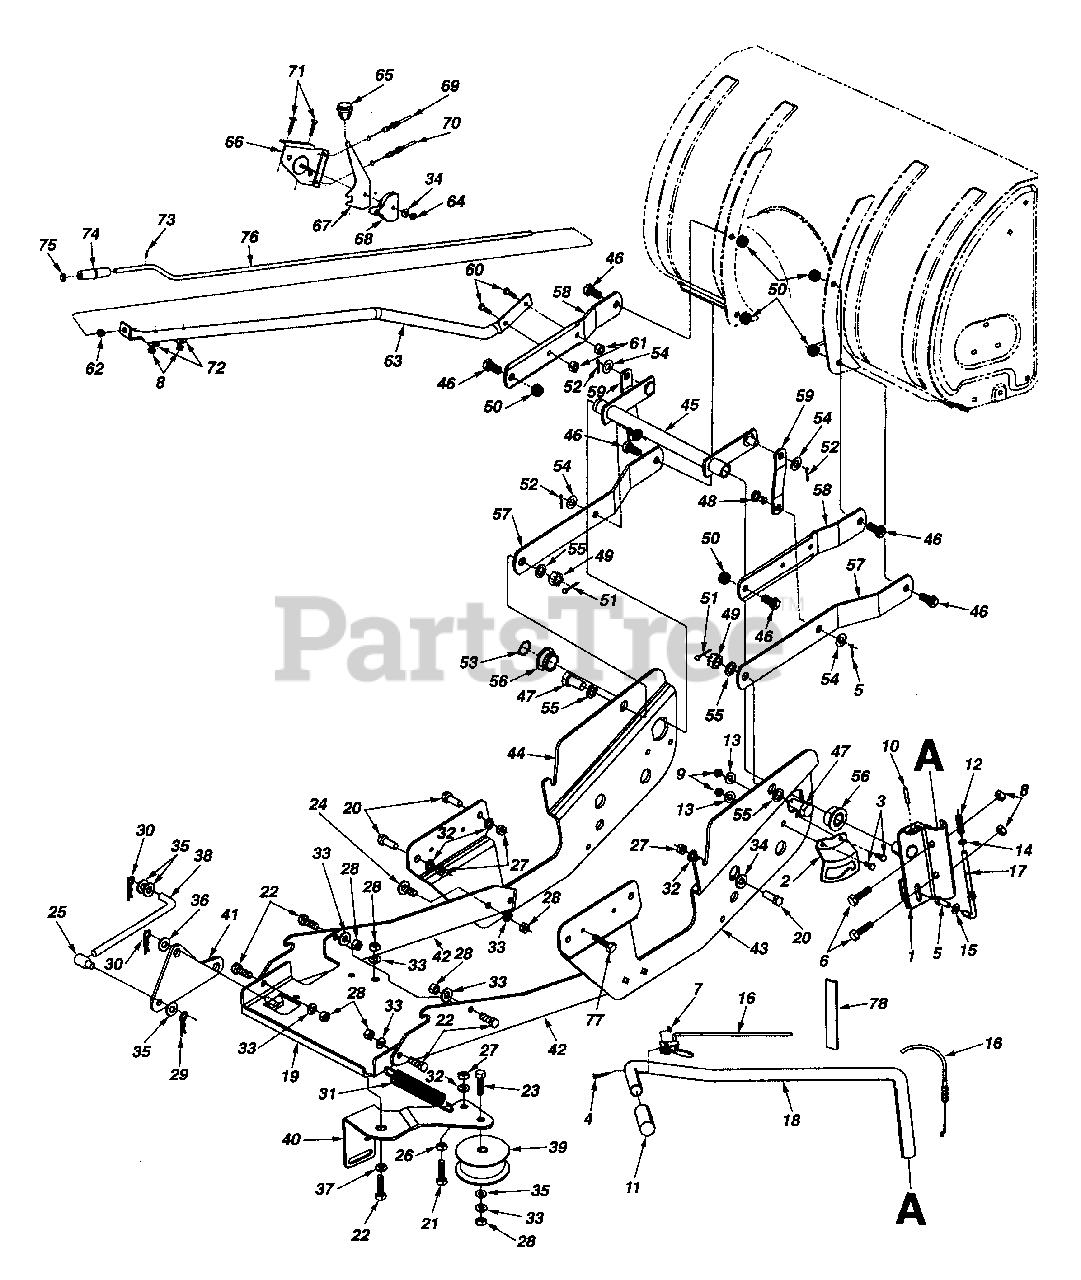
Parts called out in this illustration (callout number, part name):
4	Oval C-Sunk Scr. #10-24 x 1.36" Lg.
5	Wax Wash. Hd. Scr. 5/16-18 x .87" Lg.
6	Hex Bolt 5/16-18 x 1.75" Lg.
7	Flat Weld Nut #10-24 Thd.
8	Hex Flange L-Nut 5/16-18 Thd.
9	Hex Nut 5/16-18 Thd. (Gr. 5)
10	Spring Pin 1.5" Lg.
12	Ext. Spring 1.75" Lg.
13	L-Wash. 5/16" I.D.
14	Fl-Wash. .385" I.D. x .62" O.D.
15	Fl-Wash. .194" I.D. x .62" O.D.
16	Lift Cable
17	Lift Index Rod
18	Lift Handle Tube
21	Hex Bolt 5/16-18 x 2.25" Lg.
22	Hex Bolt 3/8-16 x 1" Lg.
23	Hex Bolt 3/8-16 x 2" Lg. (Gr. 5)
24	Carriage Bolt 3/8-16 x 1" Lg. (Gr. 5)
25	Ferrule 3/8-24 Thd.
26	Hex Jam Nut 5/16-18 Thd.
27	Hex Nut 5/16-18 Thd. (Gr. 5)
28	Hex Nut 3/8-16 Thd. (Gr. 5)
29	Hairpin Clip 1.42" Lg.
30	Hairpin Clip 1.62" Lg.
31	Ext. Spring 5.5" Lg.
32	L-Wash. 5/16" I.D.
33	L-Wash. 3/8" I.D.
34	Bell-Wash. .345" I.D. x .88" O.D.
35	Fl-Wash. .406" I.D. x .875" O.D.
36	Fl-Wash. .531" I.D. x 1" O.D.
37	Shoulder Spacer
38	Adj. Clutch Control Rod
39	Idler Pulley
47	Hex Bolt 5/8-18 x 1.25" Lg. (Gr. 5)
48	Lift Bracket Pin
49	Hex Slotted Nut 5/8-18 Thd.
50	Hex Cent. L-Nut 1/2-13 Thd. (Gr. 5)
51	Cotter Pin 1.25" Lg.
52	Cotter Pin .75" Lg.
54	Fl-Wash. .51" I.D. x 1" O.D.
55	Fl-Wash. 5/8" I.D. x 1" O.D.
56	Flange Bearing w/Flats
61	Hex Flange L-Nut 5/16-18 Thd.
62	Plastic Bushing
65	Knob
68	Cable Guide
69	Chute Control Cable w/Clip
70	Chute Control Cable
71	Carriage Bolt 5/16-18 x 1.5" Lg.
72	Saddle Wash. .32" I.D.
73	Roll Pin .63" Lg.
74	Chute Crank Knob
75	Push Cap 3/8" Rod
76	Chute Crank Rod
77	Hex Wash. Hd. Tap Scr. 1/4-20 x .75" Lg.
